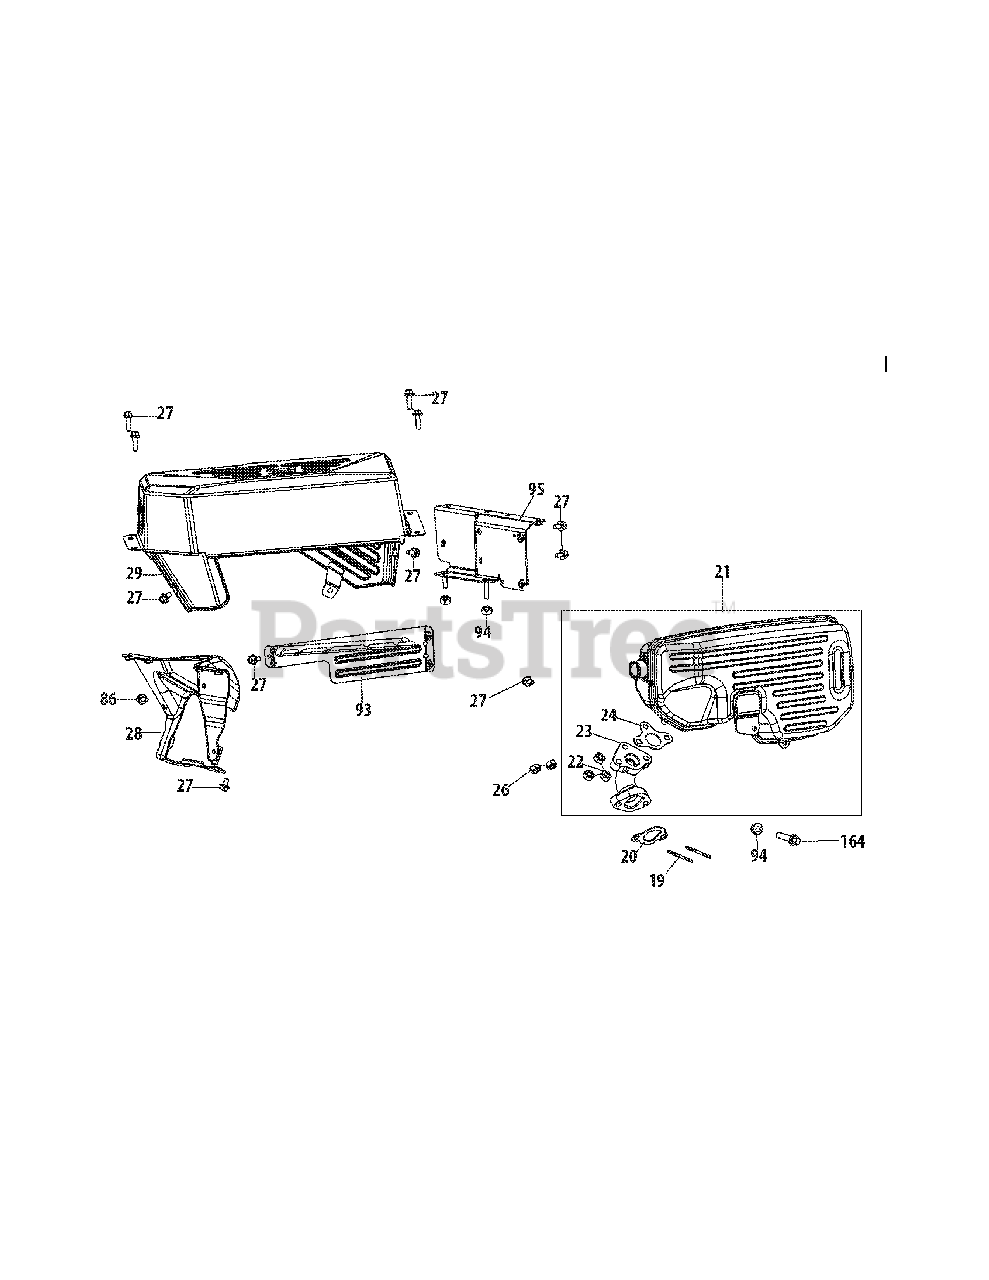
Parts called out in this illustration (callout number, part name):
19	Stud, M8×36
20	Gasket, Muffler
21	Muffler
22	Nut, M8
23	Exhaust Pipe
24	Gasket, Muffler
26	Nut, M8
27	Bolt, M6×12
28	Front Bracket, Fuel Tank
29	Muffler Guard
86	Bolt, M6×16
93	Fuel Tank Insulator
94	Nut, M6
95	Fuel Tank Bracket
164	Bolt, M6×20
